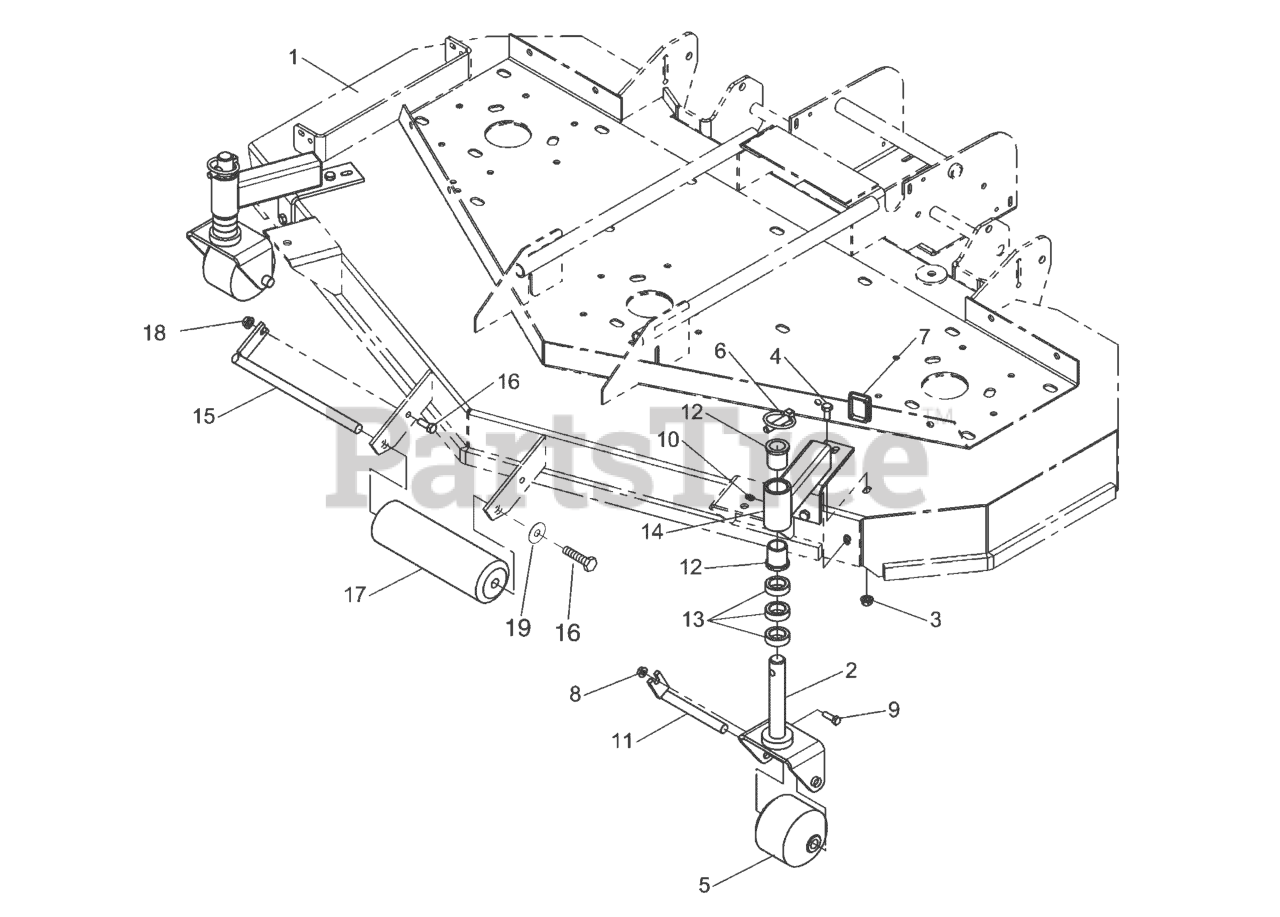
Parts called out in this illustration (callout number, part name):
1	MOWER DECK
2	WELD, CASTER YOKE
3	NUT, 3/8-16 HEX SERRATED FLANGE
4	BOLT, 3/8-16 X 1" GD5 CZ
5	ROLLER, SMALL
6	PIN, LYNCH, 7/16
7	CAP, 1-1/2 X 2 X 11GA, PLASTIC
8	NUT, 5/16-18 HEX NYLOCK FLANGE
9	BOLT, 5/16-18 X 1" GD5 YZ
10	GREASE FITTING, 1/4-28 STRAIGHT
11	WELD, CASTER ROLLER PIN
12	BUSHING, FLANGE
13	SPACER, 1.02 X 1.56 X .50
14	WELD, ARM, DECK CASTER
16	BOLT, 3/8-16 X 1" GD5 CZ
17	ROLLER, DECK
18	NUT, 3/8-16 HEX NYLOCK FLANGE
19	WASHER, .390 X 1.50 X .109 YZ
